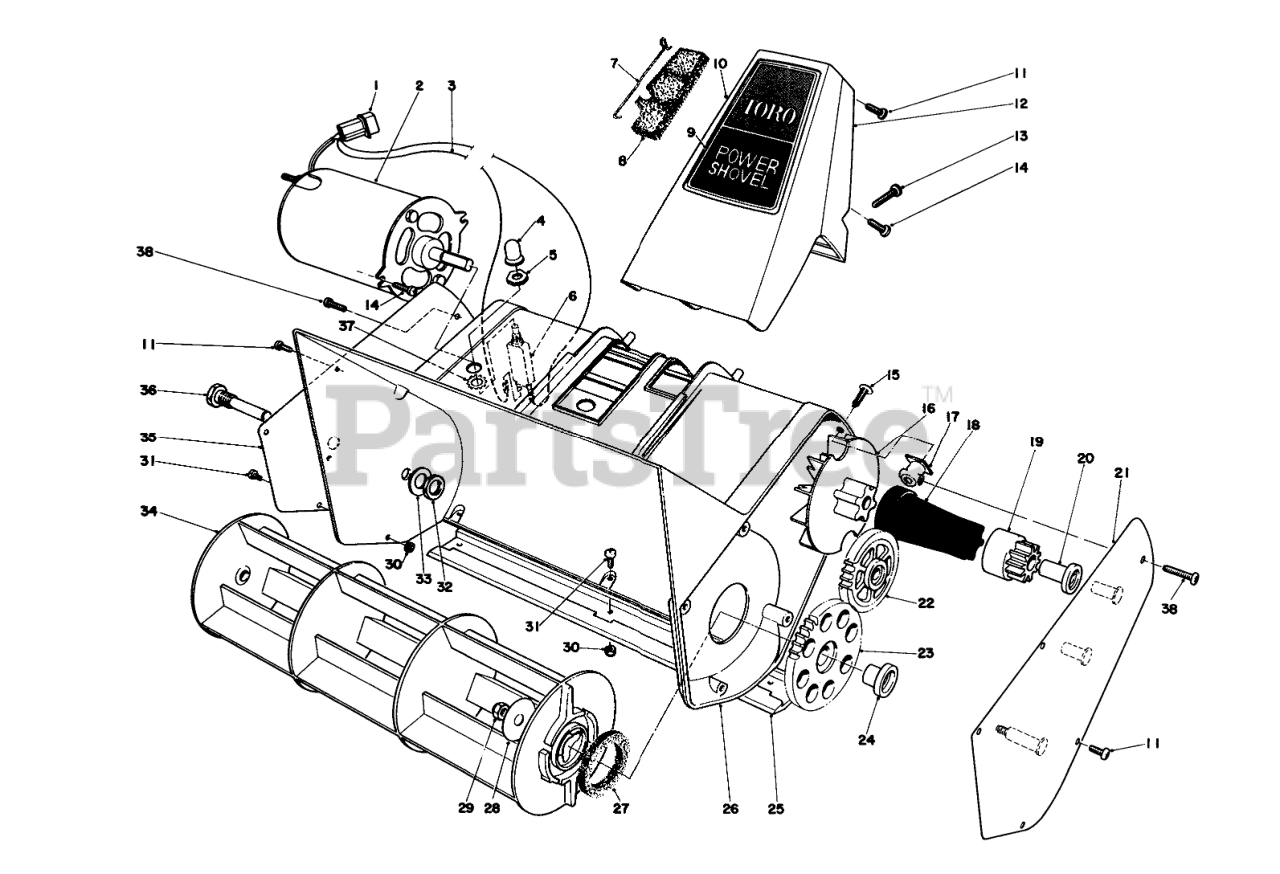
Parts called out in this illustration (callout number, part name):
1	Pin Housing
2	Motor
3	WIRE ASS'Y
4	Circuit Breaker Seal
5	Hex Nut
6	Circuit Breaker (Incl. Ref. #5)
7	RETAINER - FILTER
8	FOAM FILTER
9	HANDLE SUPT DECAL
10	FRONT SUPPORT
11	SCREW-PPH
12	Handle Support-Back
13	SCREW-PPH
14	SCREW-PPH
15	XMAS TREE FASTENER
16	FAN, POWER SHOVEL
17	MTG BLOCK
18	DRIVE COUPLING
19	Drive Gear (Incl. Ref. #20)
20	BUSHING, DRIVE GEAR
21	Gear Carrier
22	Idler Gear
23	Rotor Gear (Incl. Ref. #24)
24	BUSHING, ROTOR GEAR
25	Scraper
26	HOUSING
27	FELT WASHER
28	ROTOR WASHER
29	NUT-LOCK, NI
30	NUT-LOCK
31	SCREW-PPH
32	3/8 24 JAM NUT
33	WASHER-FLAT
34	ROTOR
35	RT. SIDE COVER (RAW)
36	ROTOR PIN
37	WASHER-LOCK/EXT
38	Screw
